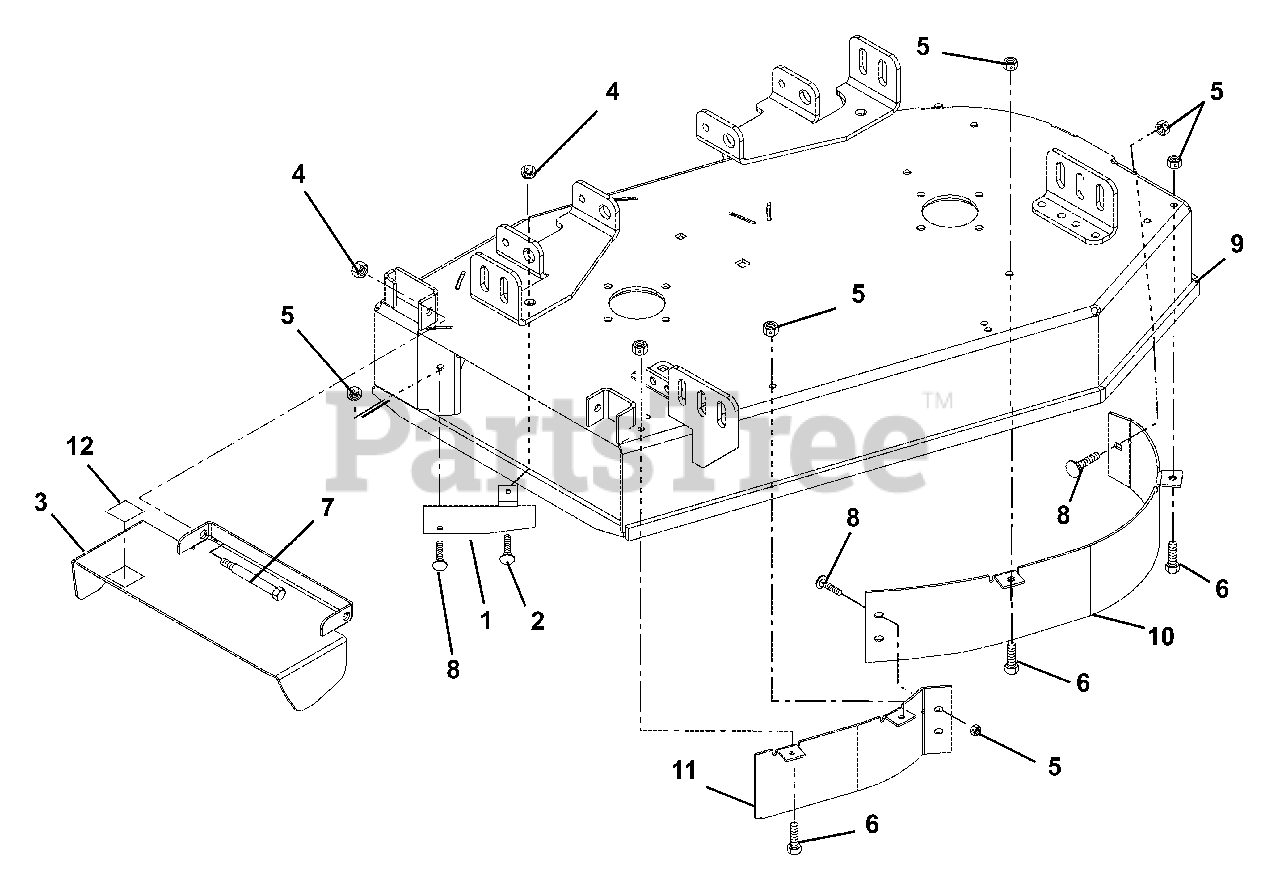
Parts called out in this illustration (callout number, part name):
1	BAFFLE, DEFLECTOR
2	@BLT-RDHDSQNK .38-16X1.00 G5YZ
3	WMT, 34" DISCHARGE CHUTE-CE
4	@NUT-LK-TOP-FLG .38-16 YWZC
5	@NUT-LK-TOP-FLG .31-18 YWZC
6	@BLT-HEX .31-18X.75 GR5 YWZC
7	BLT-SHLDR .38-16X.38 SKH
8	@BLT-RDHDSQNK .31-18X.75 G5YZ
9	WMT, 34" DECK
10	BAFFLE, 34" FRONT LH
11	BAFFLE, 34" FRONT RH
12	GRIP, PEDAL 1.50 X 3.00
